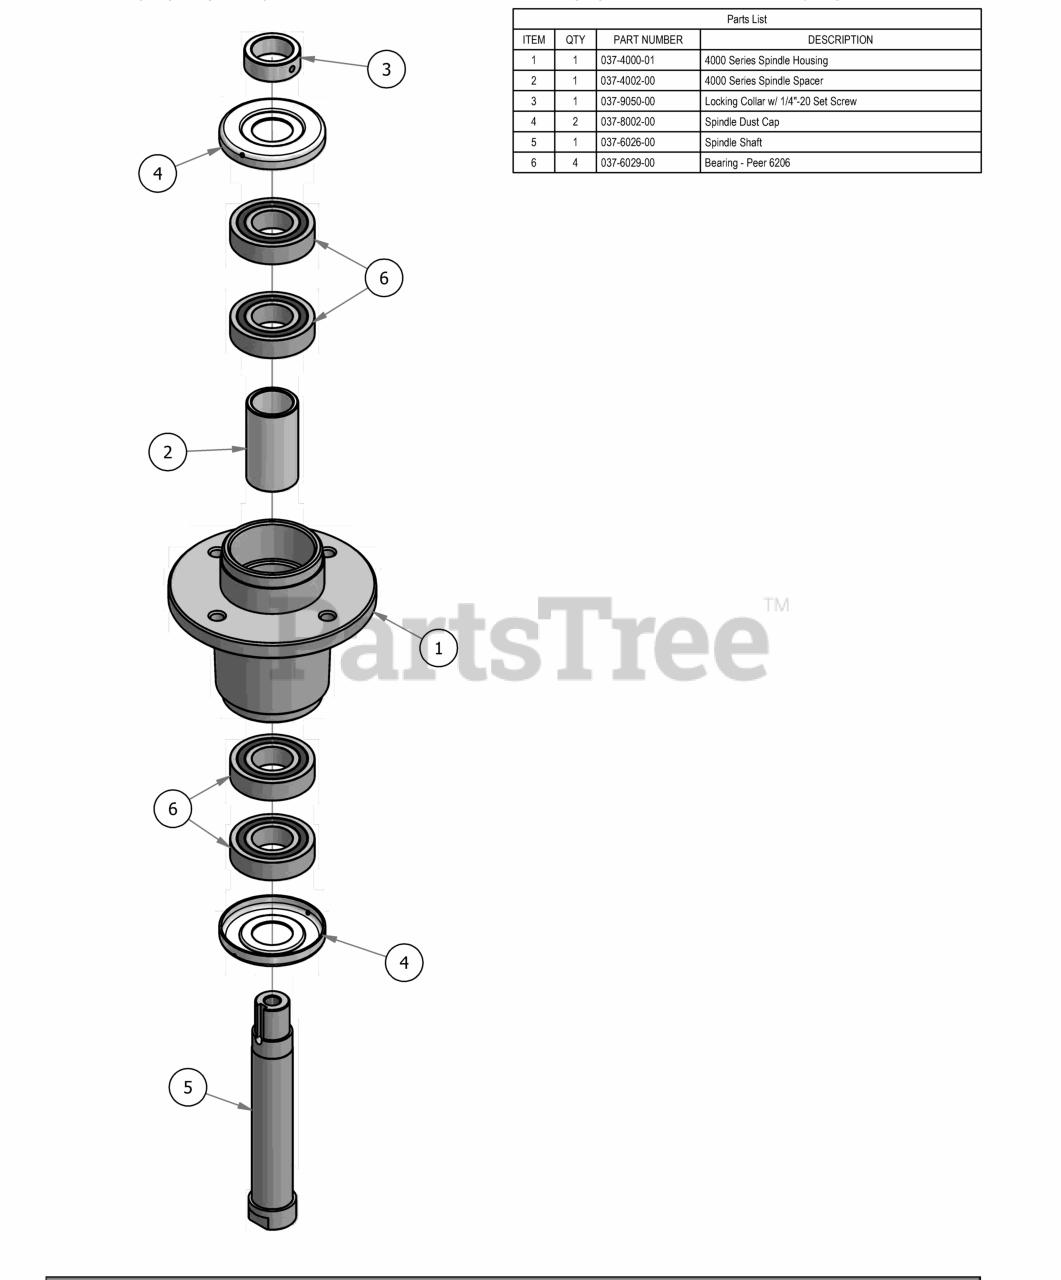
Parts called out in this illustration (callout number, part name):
1	4000 Series Spindle Housing
2	4000 Series Spindle Spacer
3	Locking Collar w/ 1/4"-20 Set Screw
4	Spindle Dust Cap
5	Spindle Shaft
6	Bearing - Peer 6206
